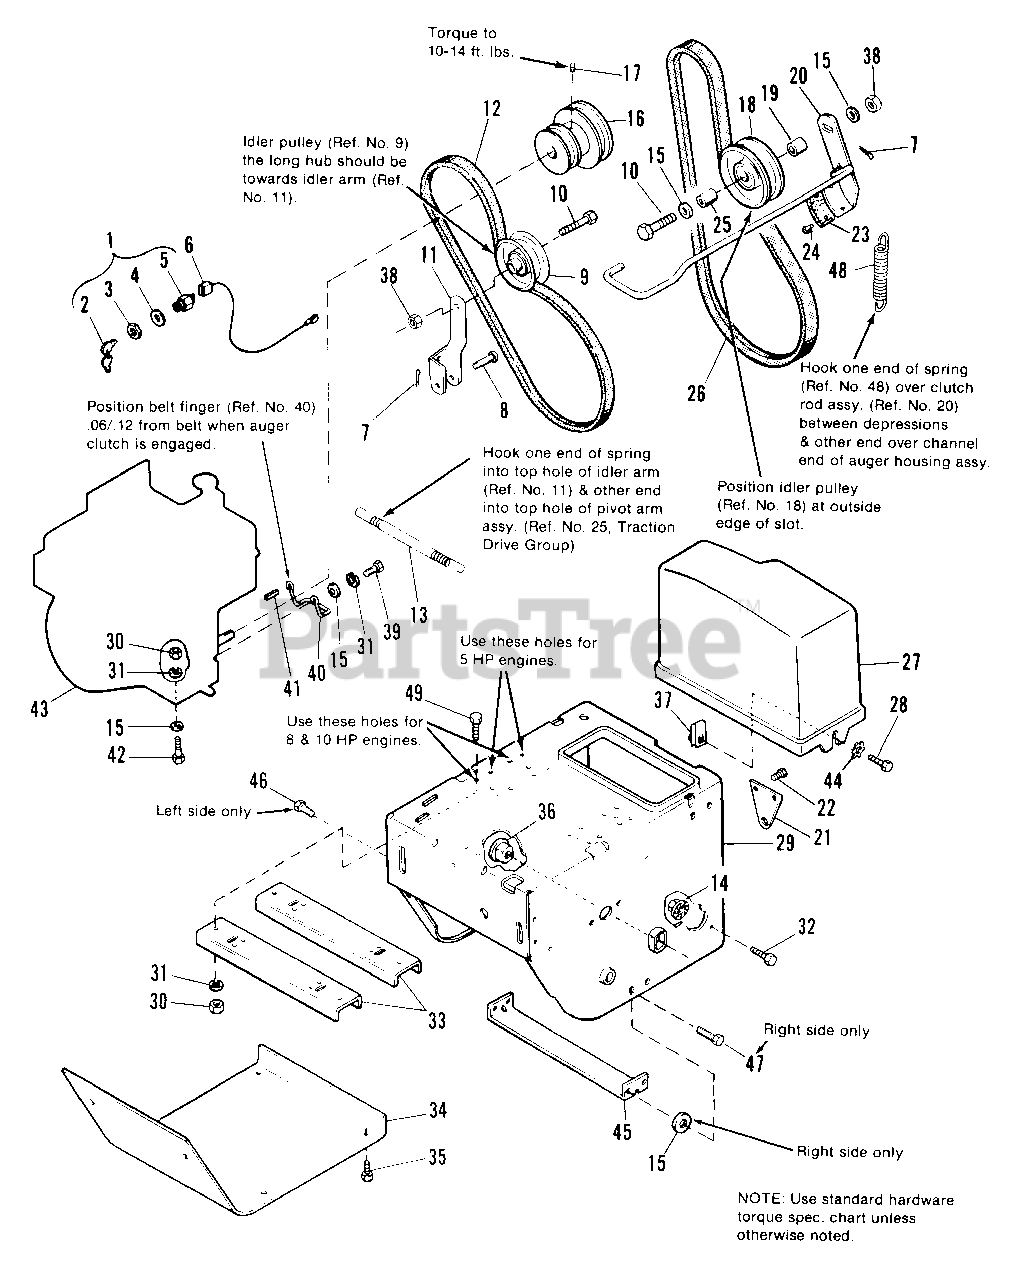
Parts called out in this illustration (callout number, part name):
1	SWITCH, Key (Inc. Ref. Nos. 2, 3, 4 & 5)
2	KEYS
3	NUT, Hex, 5/8-32
4	LOCKWASHER, Int. 5/8
6	WIRE, Ground
7	PIN, Cotter, 1/8 x 3/4
8	PIN
9	PULLEY, Idler
10	CAPSCREW, Hex Hd., 3/8-16 x 1-1/2
11	ARM, Idler, Traction
12	BELT, Traction
13	SPRING, Idler
14	NUT, Hex, Whizlock, 5/16-18
15	WASHER, Flat, 5/16
16	PULLEY, Engine
17	SETSCREW, Socket Hd., 5/16-18 x 5/8
18	PULLEY ASSY.
20	CLUTCH ROD ASSY. (Incl. Ref. Nos. 23 & 24)
21	BRACKET, Clutch Pivot
22	SCREW, Taptite, 1/4-20 x 1/2
26	BELT, Auger Drive
27	GUARD, Belt
28	SCREW, Truss Hd., 5/16-18 x 3/4
29	FRAME, Main
30	NUT, Hex, 5/16-18
31	LOCKWASHER, 5/16
32	CAPSCREW, Whizlock 5/16-18 x 3/4
33	BRACKET, Engine Mounting
34	COVER, Bottom
35	SCREW, Tapttite, 1/4-20 x 3/8
36	BUSHING, Axle
37	NUT, Pal, 5/16-18
38	LOCKNUT, Jam, 3/8-16
39	CAPSCREW, Hex. Hd., 5/16-24 x 3/4
40	BELT STOP
41	KEY, 3/16 x 3/16 x 1-1/2
41	KEY, 1/4 x 1/4 x 1-1/2
42	CAPSCREW, Hex Hd., 5/16-18 x 1-3/4
42	CAPSCREW, Hex Head 5/16-18 x 2 G5
44	LOCKWASHER, Ext. Tooth, 5/16
45	SUPPORT, Tie Bar
46	SCREW, Taptite, 5/16-18 x 3/8 (left side only)
47	SCREW, Taptite, 5/16-18 x 3/4 (right side only)
48	SPRING, Brake
49	CAPSCREW, Hex Hd., 5/16-18 x 3/4
